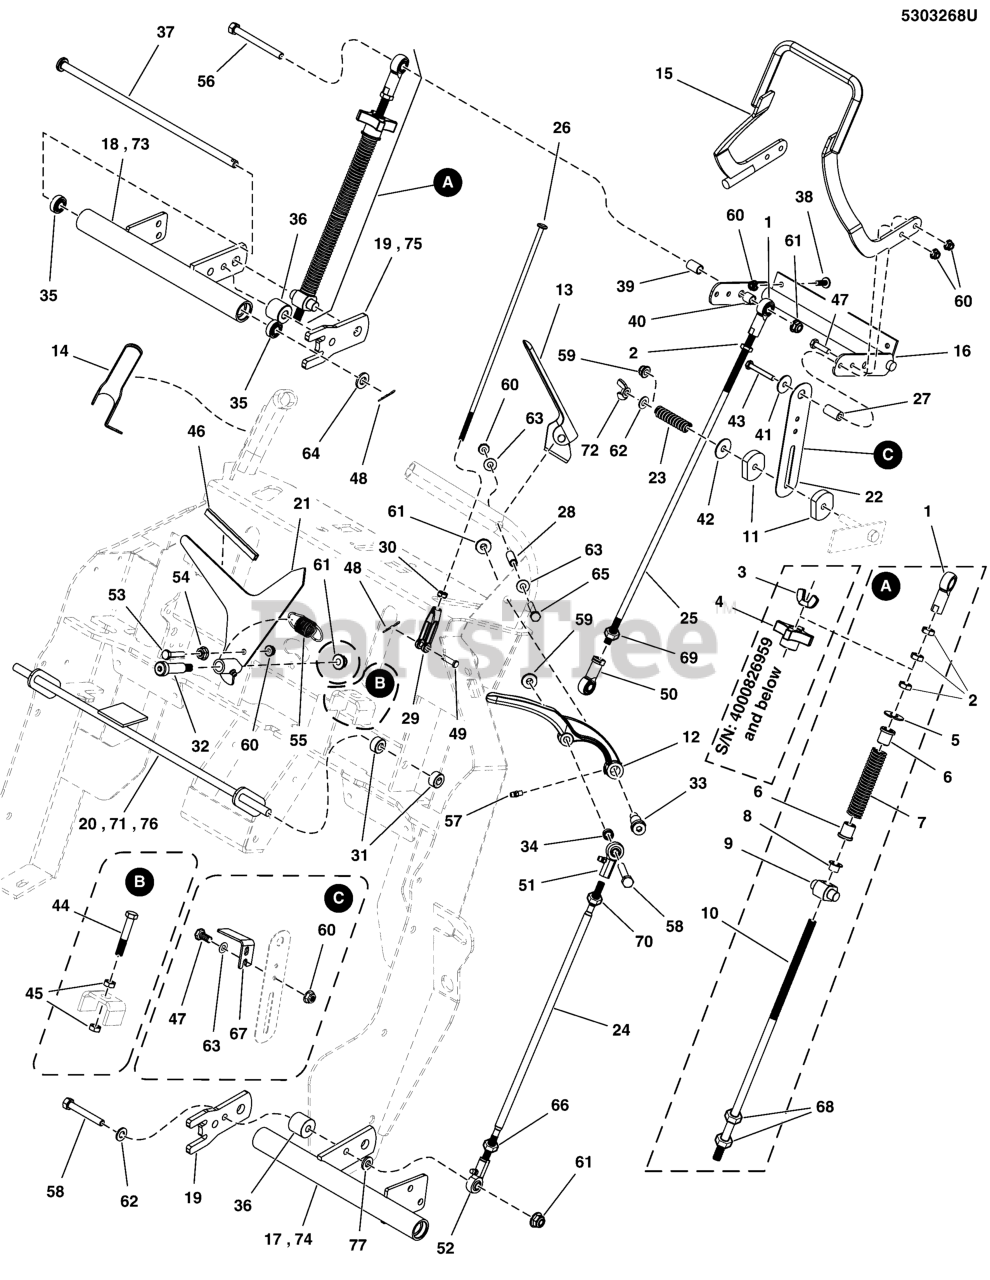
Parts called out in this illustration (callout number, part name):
1	BALL JOINT, 3/8-24 FEMALE
2	NUT, 3/8-24 HEX
3	WING NUT, 3/8-24, CZ
4	KNOB, 4 ARM, 3/8-24
5	WASHER, 3/8 USS
6	FLANGED BUSHING, 3/8IDX.63ODX.8125FL
7	SPRING,COMP,.645IDX8.00LGX.080WR,BLK E-C
8	BUSHING, .38ID X .47 OD X .38L, FL
9	TRUNION, 1/2" POSTS, STAINLESS
10	ROD, CONTROL SYSTEM, WALK
11	PAD, T-712 FRICTION MATERIAL
12	HANDLE, REVERSING - BLK
15	WELD, SPEED BAR - BLK
17	WELD, CENTER PIVOT HUB, LH - WALK - BLK
18	WELD, CENTER PIVOT HUB, RH - WALK - BLK
19	TAB, CONTROL PIVOT - BLK
20	WELD, OPC ROD, WALK - BLK
21	WELD, SPEED INDICATOR, LOCKOUT - BLK
22	PLATE, FRICTION CONTROL, SS
23	SPRING, COMP, .40 X .60 X 2.25, BLACK
24	ROD, 5/16-24 X 15.48, LH-RH, CZ
25	ROD, 3/8-24, 19.00, LH-RH CZ
26	ROD, OPC LINK, SNP PRO WB
27	SPACER, .26 X .50 X 1.00
28	SPACER, .26 X .38 X 1.25, CZ
30	HN, 1/4F GR5 YZ
31	COLLAR, 3/8 SET
32	BOLT-3/8-16 x 1-1/2, 1/2 SHOULDER
33	BOLT, 3/8-16 X 1/2, 1.00 SHOULDER, CZ
34	SPACER, .33 X .50 X .25, PM, CZ
35	BEARING, .375" ID X .875" OD X .341" THK
36	SPACER, .33 X 1.00 X .88, CZ
37	ROD, 3/8 X 12, HEADED - CZ
38	SCREW-TRUSS HD TORX DR 1/4-20X0.750 T27
39	SPACER, .38 X .50 X .75
40	SPACER, .38 X .50 X .50
41	WASHER, 1/4 FENDER
42	WASHER, 5/16 FENDER
43	BOLT, 1/4-20 X 2", GD5
44	BOLT, 1/2-20 X 2-1/2, FLT
45	NUT, 1/2-20 HEX JAM
46	U-CHANNEL, RPVC #6236 x 4"
47	BOLT, 1/4-20 X 3/4 GD5 CZ
48	PIN, COTTER, 1/8 X 1-1/4
49	PIN, CLEVIS, 1/4 X 7/8, PLATED
50	BALL JOINT, 3/8-24 FEMALE, LH
51	BALL JOINT 5/16-24 RH FEMALE BRONZE RACE
52	BALL JOINT 5/16-24 LH FEMALE BRONZE RACE
53	BOLT, 1/4-20 X 1-1/4 GD5 CZ
54	NUT, 1/4-20 HEX SERR. FLANGE
55	SPRING, EXT, 0.525 X 0.058 X 2.250 SS
56	BOLT, 3/8-16 X 3" GD5 CZ
57	GREASE FITTING, 1/4-28 STRAIGHT
58	BOLT, 5/16-18 X 2-1/4 GD5 CZ
59	NUT, 5/16-18 HEX NYLOCK FLANGE
60	NUT, 1/4-20 HEX NYLOCK FLANGE
61	NUT, 3/8-16 HEX NYLOCK FLANGE
62	WASHER, 5/16" SAE
63	WASHER, 1/4 SAE
64	WASHER, 3/8 SAE
65	BOLT, 1/4-20 X 1-3/4 GD5 CZ
66	NUT, 5/16-24 HEX, LH
67	BRACKET, SWITCH ENGAGEMENT - BLK
68	NUT, 3/8-16 HEX
69	NUT, 3/8-24 HEX, LH
70	NUT, 5/16-24 HEX
71	WELD, OPC ROD, WALK - BLK
72	NUT, Wing, 5/16-18
73	WELD, W35 CONTROL PIVOT, RH - BLK
74	WELD, W35 CONTROL PIVOT, LH - BLK
75	TAB, PIVOT, W35 - BLK
76	WELD, OPC ROD, WALK BEHIND - BLK
77	WASHER, 5/16 F436 FLAT
